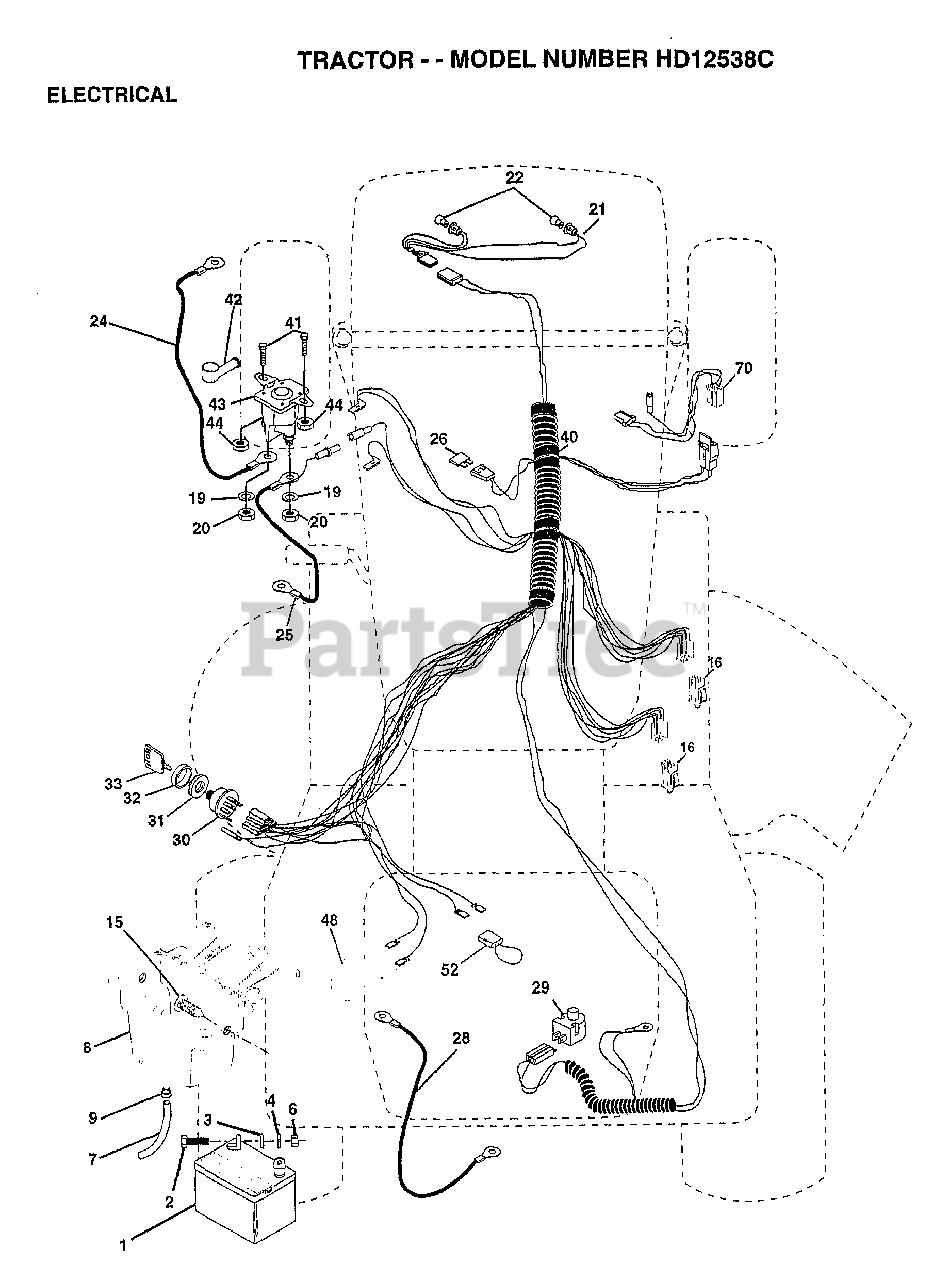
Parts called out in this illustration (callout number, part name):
2	BOLT LT
3	WASHER
4	LOCKWASHER
7	TUBE T
8	"CASE,BATTERY.MECH"
9	HOSE CLAMP T
15	FASTNER.SNAP-IN
16	SWITCH INTERLOCK
20	NUT
21	"HARNESS,LIGHT SOC"
22	HEADLAMP BULB
24	"CABLE T, BATTERY"
25	CABLE.BTRY.6GA.RD
26	FUSE HYT
28	CABLE T
29	SWITCH SEAT
30	SWITCH IGN 4POS
31	NUT IGNITION
32	COVER KEY SWITCH
33	KEY
40	HARNESS-IGNITION
41	BOLT HXHD FIN
44	NUT HXKEP 1/4X20
48	ADAPTER AMMETER
52	PROTECTION LOOP
70	HARNESS ENG DUAL
